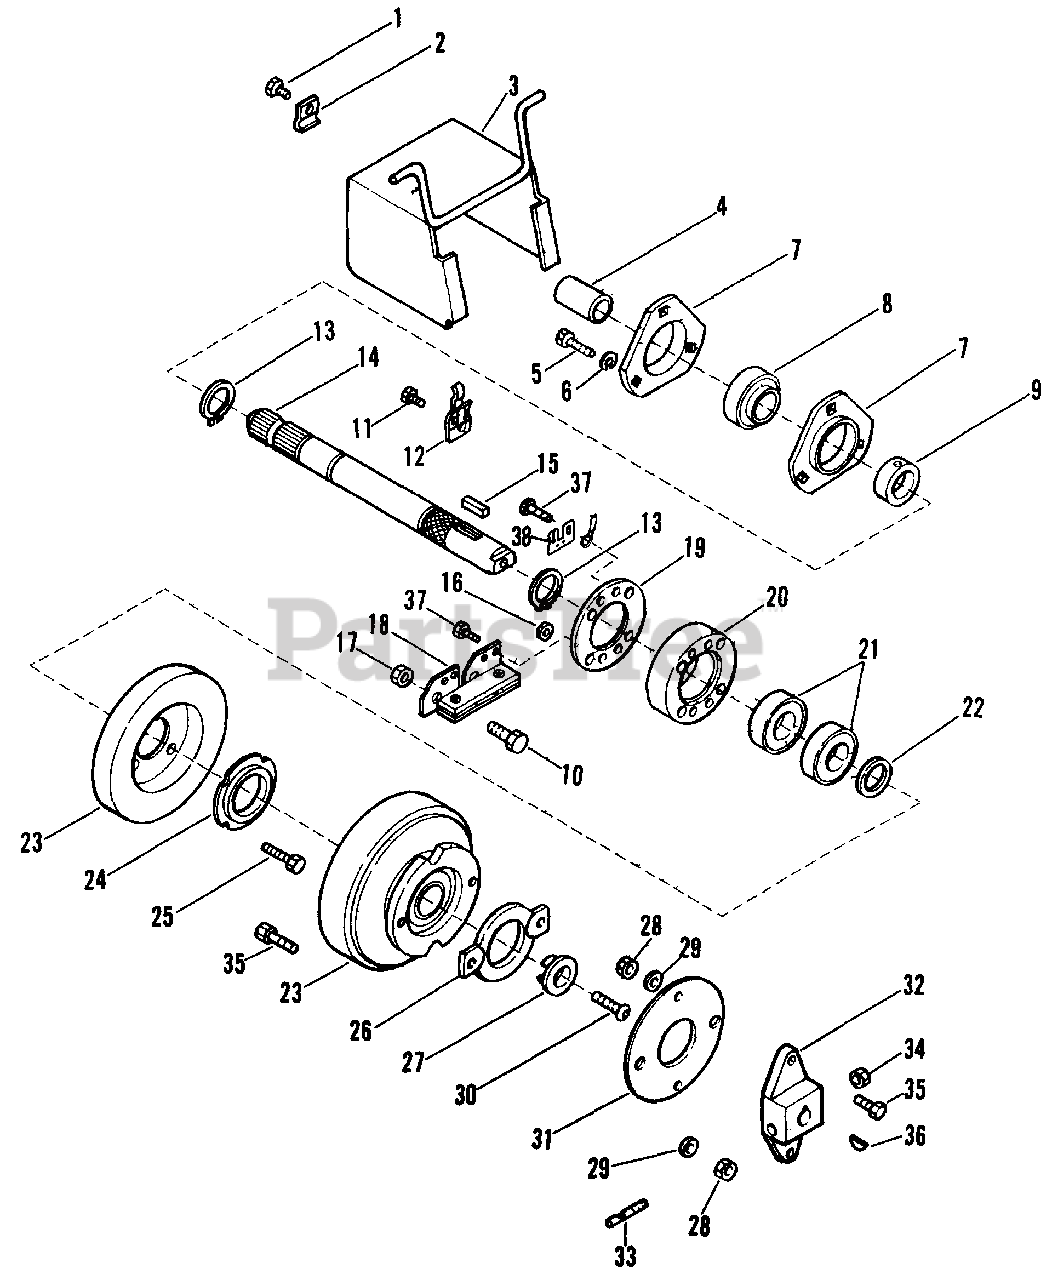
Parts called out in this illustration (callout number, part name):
1	Taptite, 1/4-20 x .50
2	Clip
3	PTO Shield
4	Shaft Cover
5	Bolt, Hex 5/16-18 x .75
6	Washer, Lock 5/16 SP
7	Bearing Flange
8	Ball Bearing, 1" I.D. x 2-3/64 O.D.
9	Bearing Collar
10	Bolt, Hex 5/16-18 x 1.50
11	Screw, Taptite #10-24 x .375
12	Snap Fastener
13	Ring, Retaining
14	Shaft
15	Key, Square .25 x 1.00
16	Nut, Torque Lock #10-24 Gr A
17	Nut, Lock 5/16-24
19	Ring
20	Bearing Mount
21	Bearing, Ball
22	Washer, 1.031/1.046 x 1.375 x .055
23	Electric Clutch
24	Bearing Flange
25	Screw, Mach. No. 10-24 x 1.25 Pan
26	Pilot Plate
27	Retainer
28	Nut, Lock 5/16-18
29	Washer, Flat .375 x .734 x .065
30	Screw, Cap BTHD 3/8-16 x 1.25
31	Spacer Coupling
32	Coupling
33	Lock Stud
34	Nut, Lock 3/8-16
35	Bolt, Hex 5/16-18 x .875
36	Key, Woodruff .187 x .75 #9
37	Taptite, #10-24 x .75
38	Clip, Connector Mounting
NS	Rear PTO Decal, 3200 RPM
